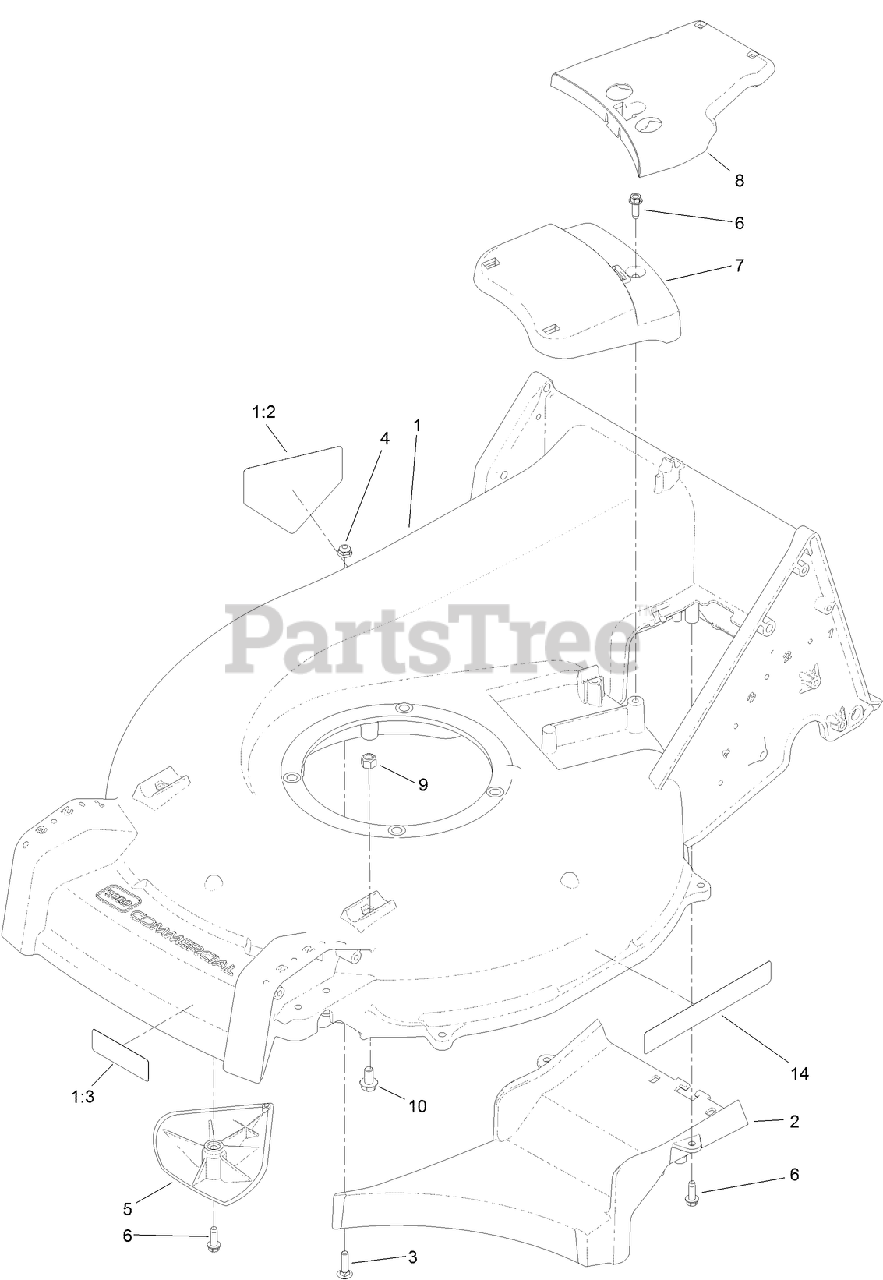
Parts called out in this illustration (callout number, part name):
1	HOUSING ASM
1:2	DECAL-DANGER
1:3	DECAL-WARNING, BLADE
2	FLOOR-CHUTE
3	SCREW-CARR
4	NUT-HF
5	KICKER
6	SCREW-HWHTF
7	COVER-BELT, FRONT
8	COVER-BELT, REAR
9	NUT-LOCK, NI
10	SCREW-HHF
14	DECAL-RECYCLER
